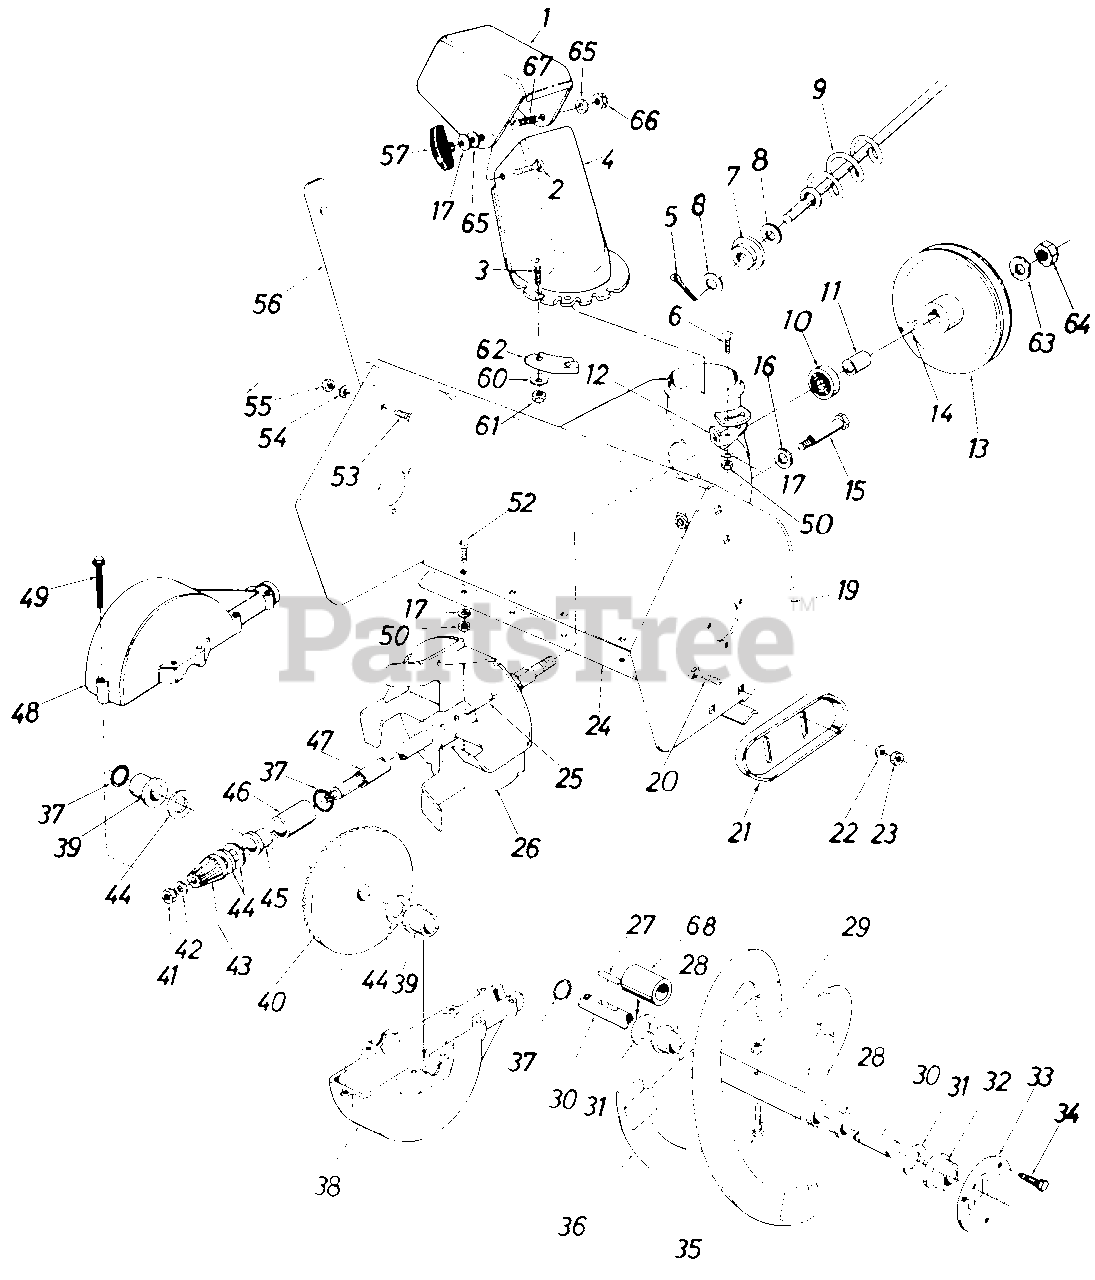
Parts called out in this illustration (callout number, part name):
1	Upper Chute
2	Carriage Bolt 5/16-18 x 1.0"*
3	Truss Mach. Scr. 1/4-20 x .75"*
4	Lower Chute
6	Carriage Bolt 5/16-18 x 75
7	Bushing
8	Fl-Wash. .385 I.D. x .62" O.D.
9	Chute Crank Ass'y.
10	Ball Brg. .62" I.D. x 1.38" O.D.
11	Spacer .63" I.D. x .88" O.D. x 900" Lg.
13	1/2" "V"-Pulley .625" I.D. x 7.50" O.D.
14	#61 Hi-Pro Key 3/16" x 5/8" Dia.
15	Shld. Bolt .50" Dia. x 2.11"
16	Bell-Wash. .40" I.D. x .88" O.D. x .06
17	Bell-Wash. .34" I.D. x .88" O.D.
19	20" Blower Housing Ass'y.
20	Carriage Bolt 3/8-16 x .62"*
21	Slide Shoe
22	Bell-Wash. 3/8" I.D.
23	Hex Jam Nut 3/8-16 Thd.
24	20" Shave Plate
28	Flange Brg. .75" I.D. x .88" O.D.
29	Hex Ins. L-Nut 5/16-18
30	Spiral Axle
31	Fl-Wash. .75" I.D. x 1.50" O.D. x .06
32	Flange Brg. w/Flats .755" I.D.
33	Bearing Housing
34	Hex Wash. Hd. Self-Tap Scr. 5/16-24 x .62" Lg.
35	Hex Bolt 5/16-18 x 1.50" Lg.
36	20" Spiral Ass'y.-L.H.
37	"O"-Ring-3/4" I.D.
38	Bevel Gear Housing-Lower Half
39	Plastic Flange Brg. .755" I.D.
41	Hex Cent. L-Nut 5/16-24 Thd.
42	Fl-Wash. .34" I.D. x .62" O.D. x .06
43	Pinion Gear
44	Fl-Wash. .75" I.D. x 1.25" O.D. x.06
45	Flange Brg. .755" I.D.
46	Sleeve Brg. .755" I.D.
48	Bevel Gear Housing- 0 Upper Half
49	Hex Wash. Hd. Self-Tap Scr. 1/4-20 x 1.00" Lg.
50	Hex Nut 5/16-18 Thd.*
52	Carriage Bolt 5/16-18 x .62" Lg.*
53	Carriage Bolt 5/16-18 x .62n Lg.*
54	L-Wash. 5/16" I.D.*
55	Hex Nut 5/16-18 Thd.*
56	Drift Cutter Bar
57	Knob
60	Fl-Wash. 1/4" I.D.
61	Hex L-Nut 1/4-20 Thd.
62	Chute Flange Keeper
63	Fl-Wash. 54n l.D. x .94" O.D. x .06
64	Hex Jam Nut 5/8-18 Thd.
65	Fl-Wash. .344 I.D. x 1.125 O.D.
66	Hex L-Nut 5/16-18 Thd.
67	Truss Mach. Scr. 5/16-18 x 75" Lg.*
68	Spacer
